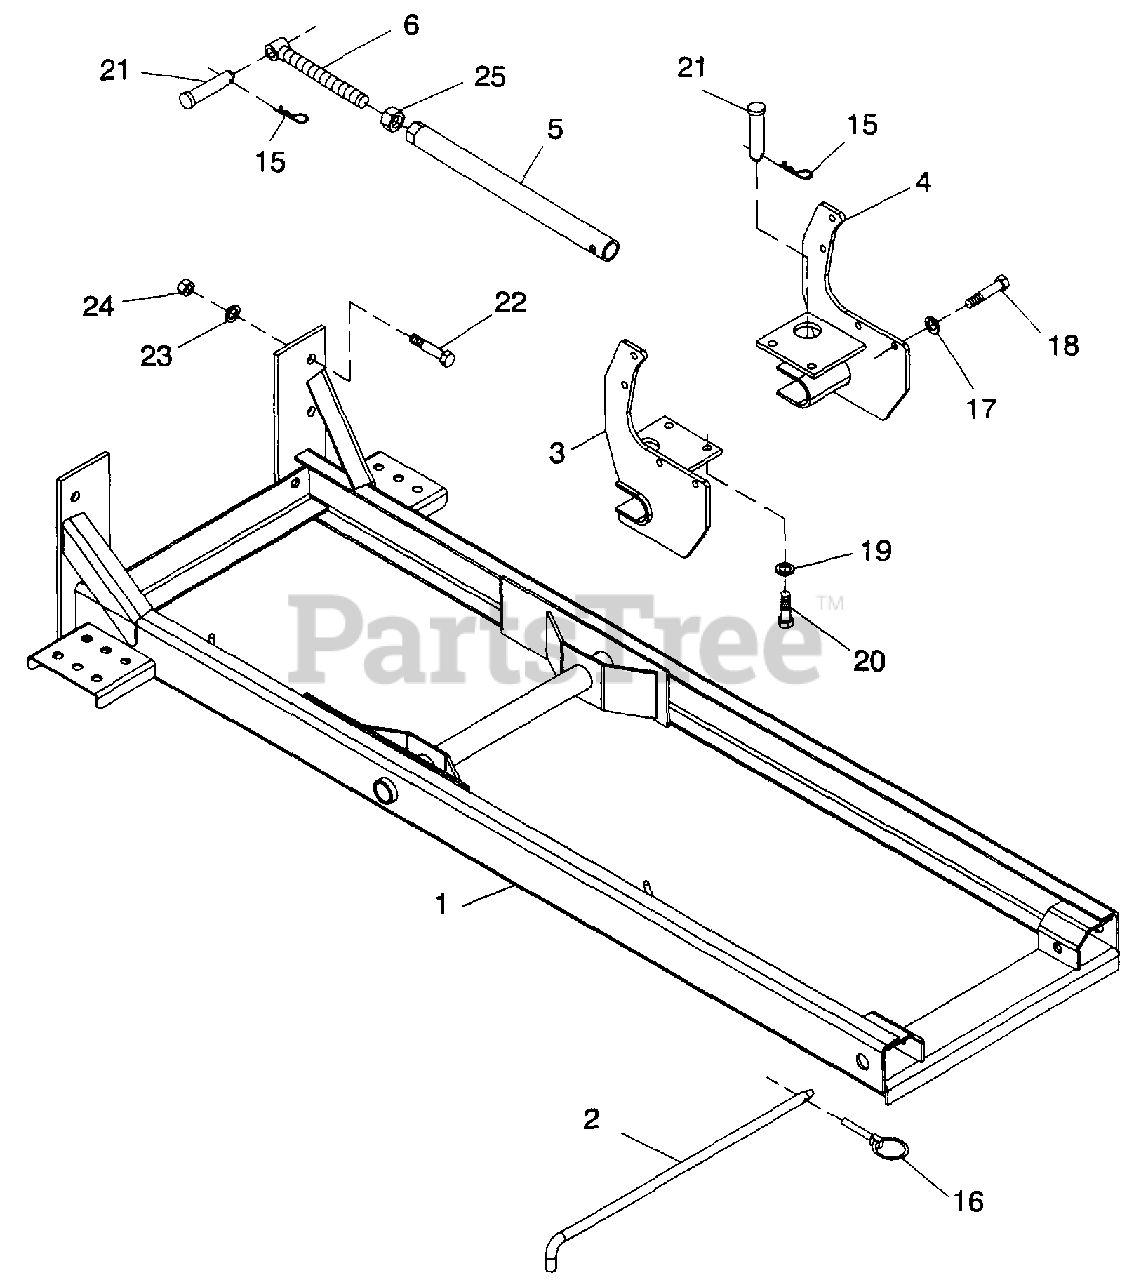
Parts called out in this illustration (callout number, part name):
1	Backhoe sub-frame
3	Left Rear Mount
4	Right Rear Mount
5	Outer link assembly, 19.5
6	Inner top link assembly
15	Hairpin cotter
16	1/4 x 1-3/4 Klik pin
17	1/2 Lockwasher
18	12mm x 1.75P x 110mm Hex head cap screw, CL 8.8
19	9/16 Standard lockwasher
20	14mm x 2.0P x 45mm Hex head cap screw, CL 8.8
21	3/4 x 2.76 Clevis pin
22	3/4 NC x 2 Hex head cap screw GR5
23	3/4 Lockwasher
24	3/4 Nut
25	1" NC Hex nut
